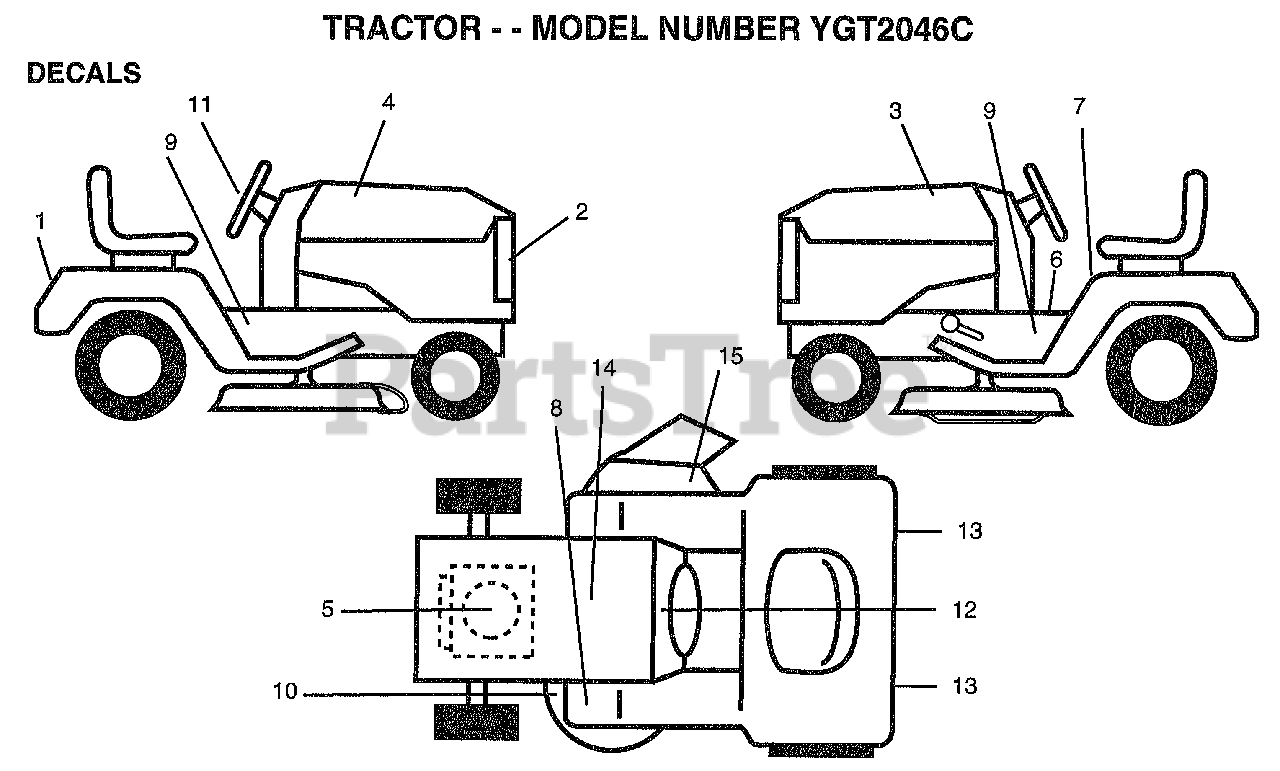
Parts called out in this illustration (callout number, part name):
1	DECAL FENDER
2	DECAL GRILLE
3	DECAL HOOD LH
4	DECAL HOOD RH
5	DECAL, ENGINE
6	DECAL BRAK PARK
7	DECAL.CAUT.ENG/FR
8	DECAL T
9	"DECAL CHASSIS,46"""
11	DECAL INS STRG WH
12	DECAL.INSTR.FRENC
13	REFLECTOR-TAIL YT
14	DECAL.BATRY.3-3908
15	"DECAL, WARNING"
